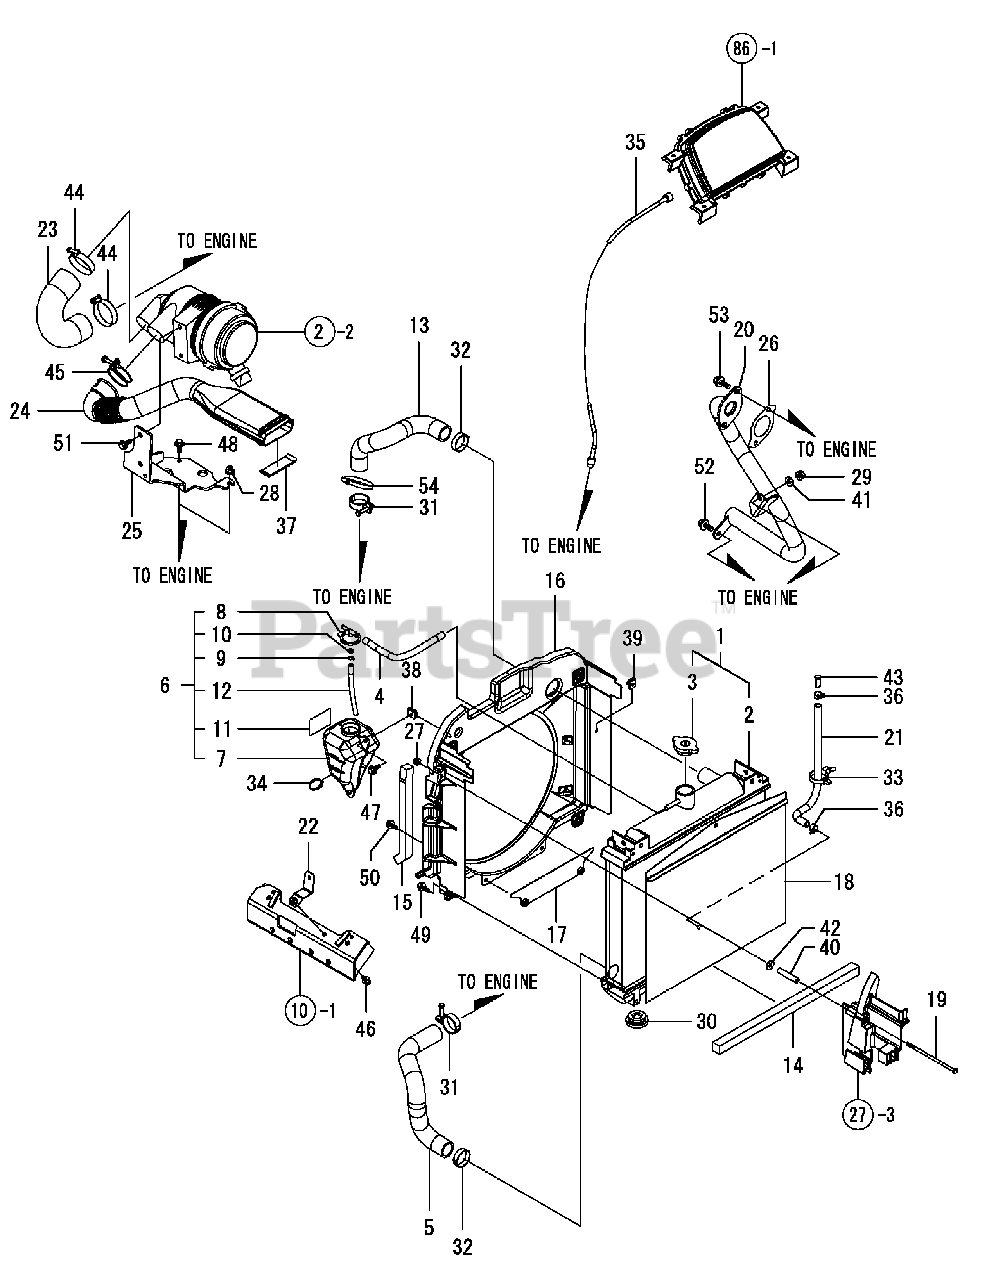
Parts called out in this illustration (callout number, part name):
3	CAP, RADIATOR D46
5	HOSE, RADIATOR, LOWER
6	TANK ASSY, COOLANT
11	LABEL, SUB-TANK
13	HOSE, WATER, UPPER
14	SEAL, RADIATOR
15	SEAL, SHROUD LOWER
16	SHROUD M ASSY, FAN
17	PLATE ASSY, SHROUD
18	SCREEN, RADIATOR
23	HOSE, AIR INTAKE
24	AIR INTAKE PIPE
25	BRACKET ASSY, AIR CLEANER
27	NUT W/WASHER 6
28	NUT W/WASHER 8
29	NUT W/WASHER 8
35	CABLE, HOUR METER
37	SEAL AIR INTAKE
40	COLLER, 6.5X10X52
41	WASHER 8, POLISHED
46	BOLT M 6X 16 PLATED
47	BOLT M 6X 16 PLATED
48	BOLT M 6X 16 PLATED
49	BOLT M 6X 16 PLATED
50	BOLT M 6X 16 PLATED
51	BOLT M 8X 16 PLATED
52	BOLT M 8X 16 PLATED
53	BOLT M 8X 25 PLATED
